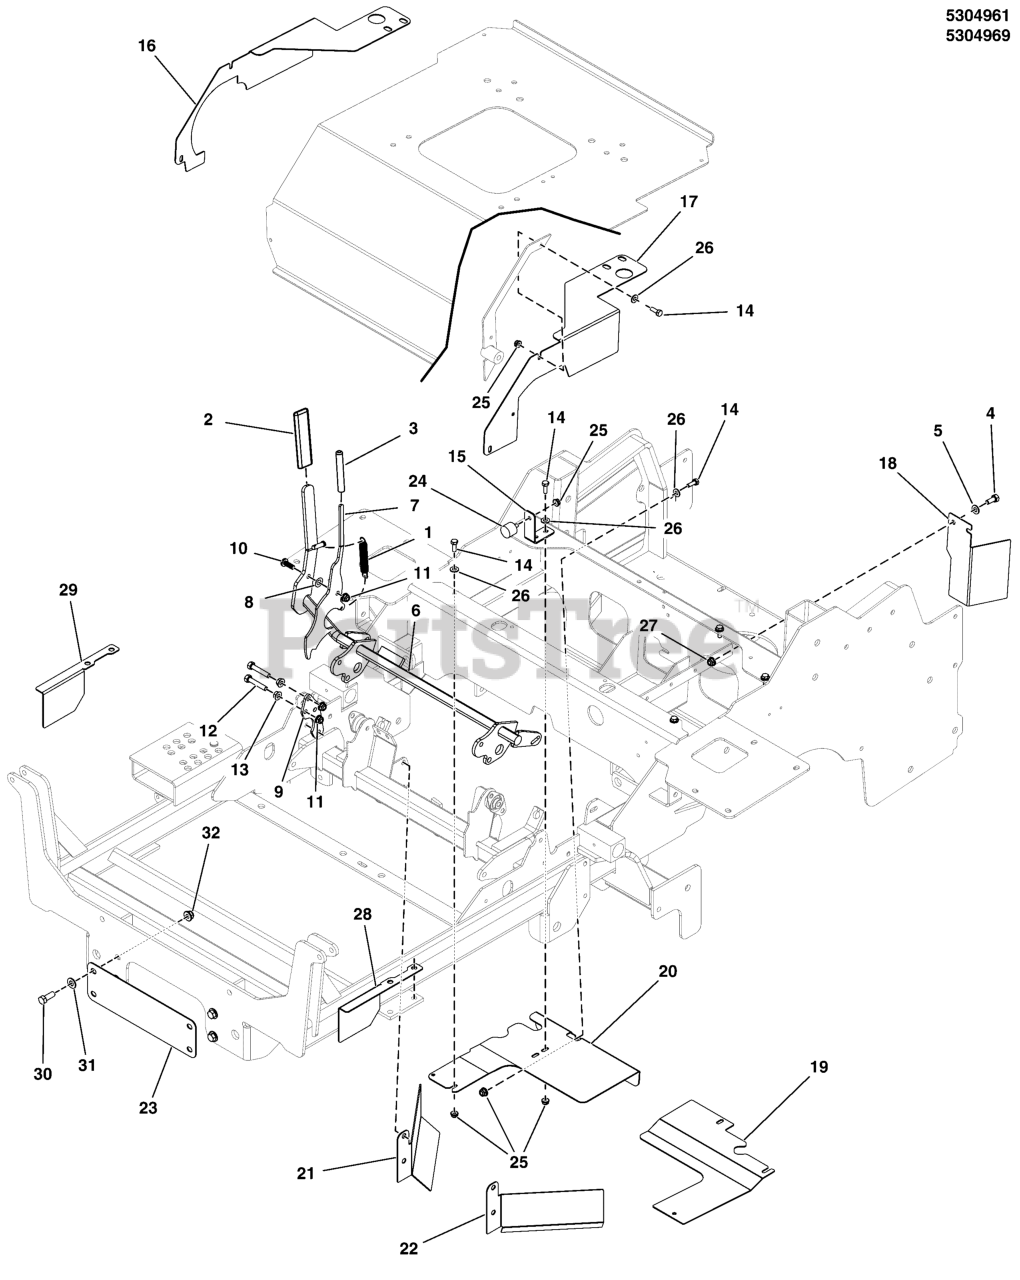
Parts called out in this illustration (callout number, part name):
1	SPRING-EXT, .500 OD X 3.50 LG X .058 WR
2	GRIP, FOAM, 1/4 X 1 X 4.1
3	COVER, VINYL HANDLE
4	BOLT, 5/16-18 X 3/4 GD5
5	WASHER, 5/16" SAE
6	WELD, HANDLE, BRAKE, IS3200 CE - BLK
7	LEVER, BRAKE, IS3200CE - BLK
8	WASHER,WAVE,M10
9	PLATE, PIVOT MNT, IS3200 CE - BLK
10	SCREW, TRUSS HD TORX DR5/16-18X0.875 BLK
11	NUT, 5/16-18 HEX NYLOCK FLANGE
12	BOLT, 5/16-18 X 1-3/4 GD5 CZ
13	NUT, 5/16-18 HEX SERRATED FLANGE (SMALL)
14	BOLT, 1/4-20 X 3/4 GD5 CZ
15	PLATE, BRACKET, SEAT LOCK - BLK
16	PLATE, GUARD, SEAT PLTFRM, RH 1S3200-RED
17	PLATE, GUARD, SEAT PLTFRM, LH 1S3200-RED
18	PLATE, GUARD, LH CE, IS3200 - RED
19	PLATE, FAN GUARD, LH CE - RED
20	PLATE, FAN GUARD, RH CE - RED
21	PLATE, CRADLE BELT GUARD, RH - RED
22	PLATE, CRADLE BELT GUARD, LH - RED
23	PLATE, FRONT FRAME GUARD, IS3200 - RED
24	BUMPER, RUBBER 1/4-20
25	NUT, 1/4-20 HEX NYLOCK FLANGE
26	WASHER, 1/4 SAE
27	NUT, 5/16-18 HEX NYLOCK FLANGE
28	PLATE, FRAME GUARD, RH - RED
29	PLATE, FRAME GUARD, LH - RED
30	BOLT, 3/8-16 X 1" GD5 CZ
31	WASHER, 3/8 SAE
32	NUT, 3/8-16 HEX NYLOCK FLANGE
